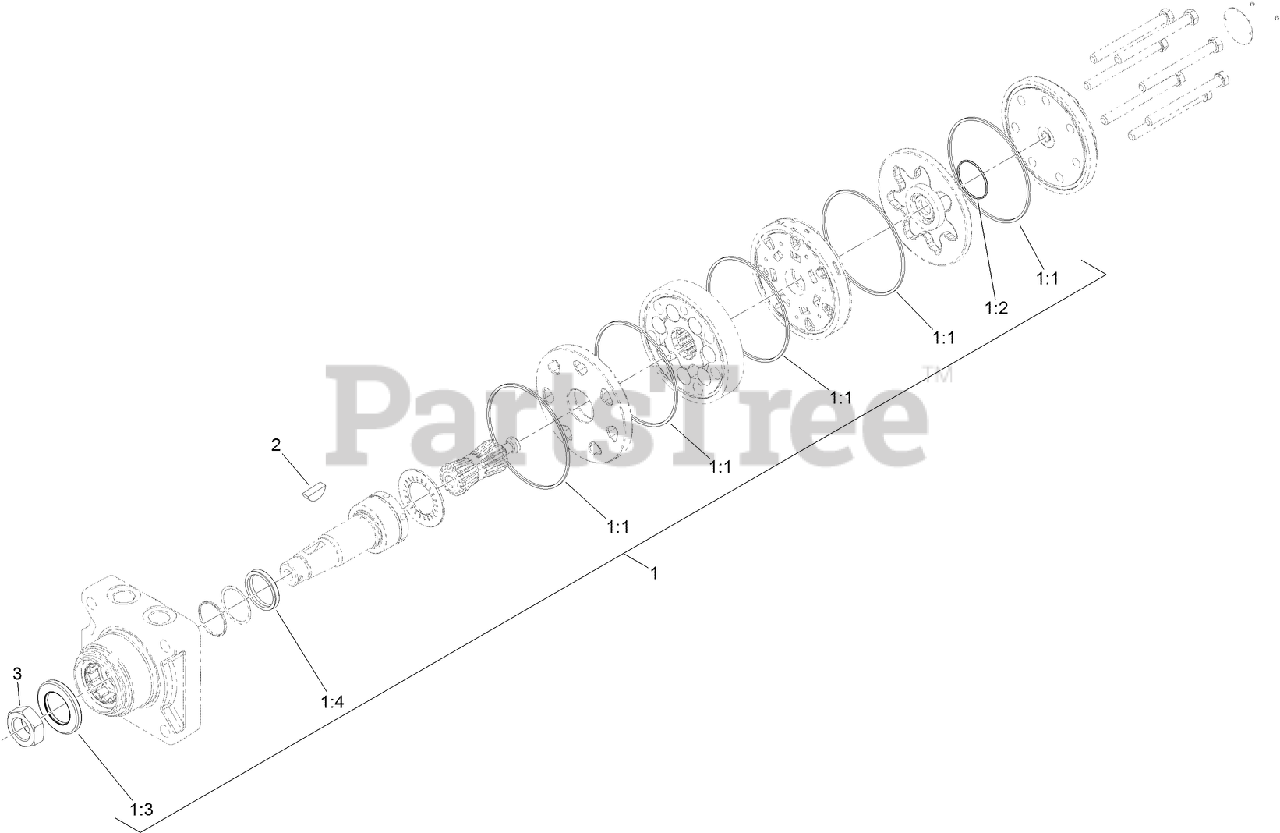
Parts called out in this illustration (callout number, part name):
1	SEAL KIT
1:1	SEAL-RING, VITON
1:2	Seal-Commutator
1:3	SEAL-DIRT/WATER, HI TEMP
1:4	SEAL-SHAFT
2	KEY-WOODRUFF
3	NUT-LOCK
